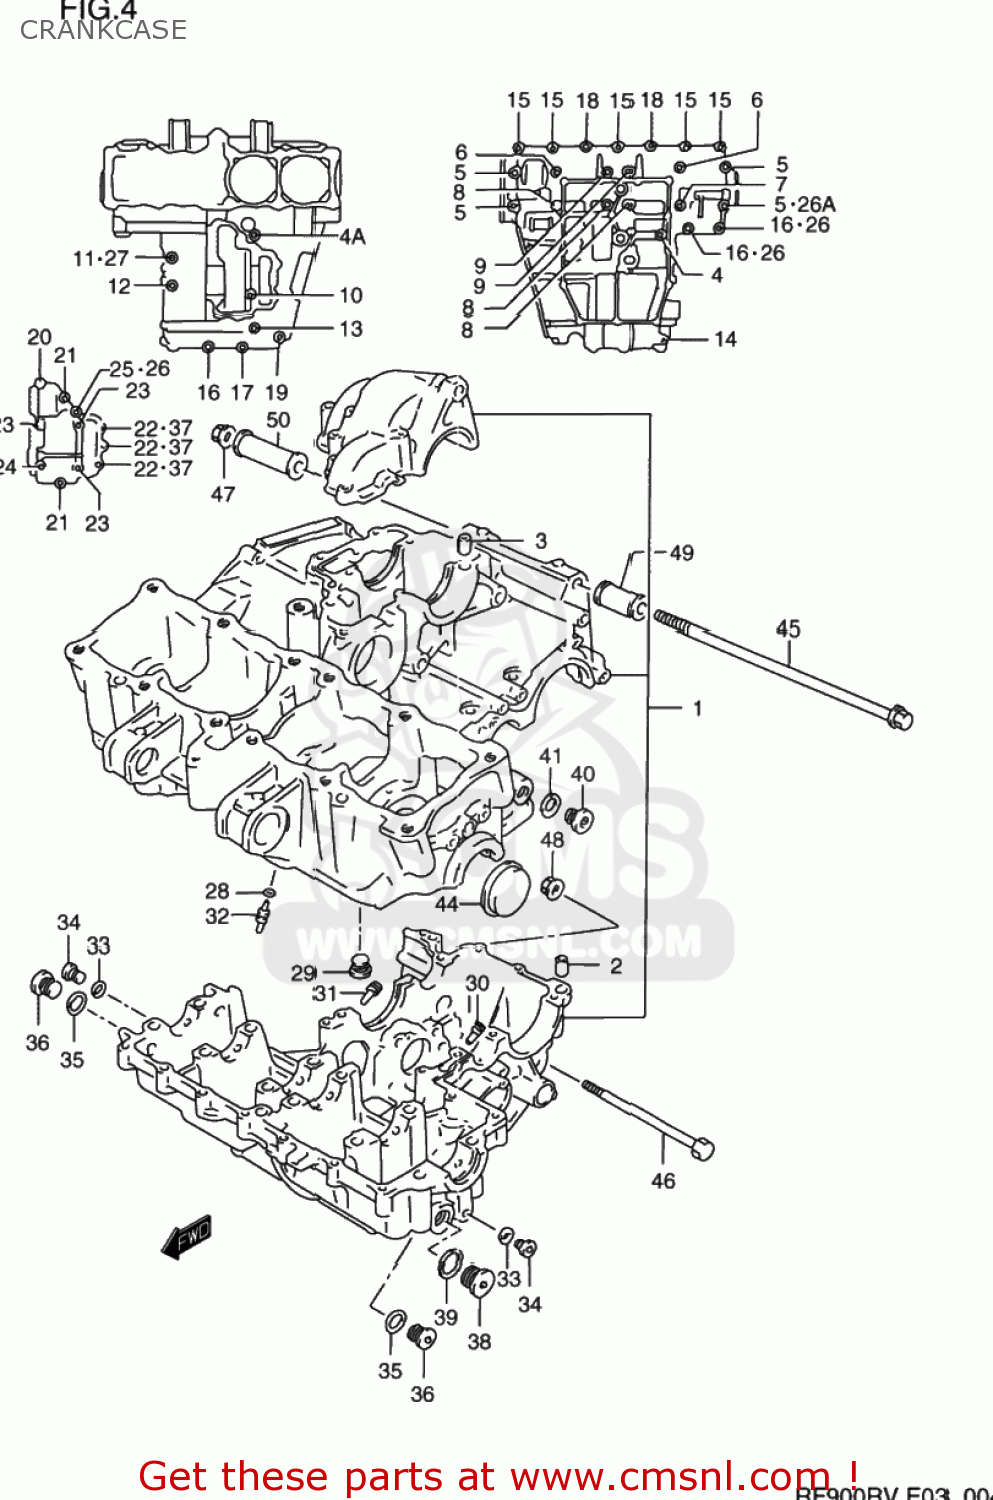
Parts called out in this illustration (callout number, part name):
1	CRANKCASE SET
2	PIN(10.4X13X22)
3	PIN
4	BOLT(6X105)
4A	BOLT(6X105)
5	BOLT 9X80
6	BOLT(9X95)
7	BOLT(9X105)
8	BOLT(9X115)
9	BOLT(9X60)
10	BOLT
11	BOLT
12	BOLT
13	BOLT
14	BOLT
15	BOLT
16	BOLT
17	BOLT
18	BOLT
19	BOLT
20	BOLT,CL.COVER
21	BOLT
22	BOLT
23	BOLT,CL.COVER
24	BOLT
25	BOLT(6X145)
26	GASKET(6.2X13X1.2) (NAS)
26A	GASKET(10.2X20X2).3 (NAS)
27	GASKET(8.2X14X1) (NAS)
28	O RING(D:1.2,ID:4)
29	PLUG,CRANKCASE,UPPER
30	JET
31	JET(140)
32	JET,OIL GALLERY
33	GASKET(10X14X3.6) (NAS)
34	PLUG(10X6.8)
35	GASKET(16X22X2) (NAS)
36	PLUG
37	GASKET(5.8X11X1.2) (NAS)
38	PLUG(22X11)
39	GASKET(22X27X2) (NAS)
40	PLUG
41	GASKET(13.8X18.8X4.8) (NAS)
42	BEARING,CRANK THRUST(GREEN)
43	BEARING,CRANK THRUST(RED)
44	PLUG
45	BOLT 10X280
46	BOLT(12X140)
47	NUT
48	NUT 12MM
49	SPACER,ENG MTG RR UPR,L(L45)
50	SPACER,ENGINE MOUNT
